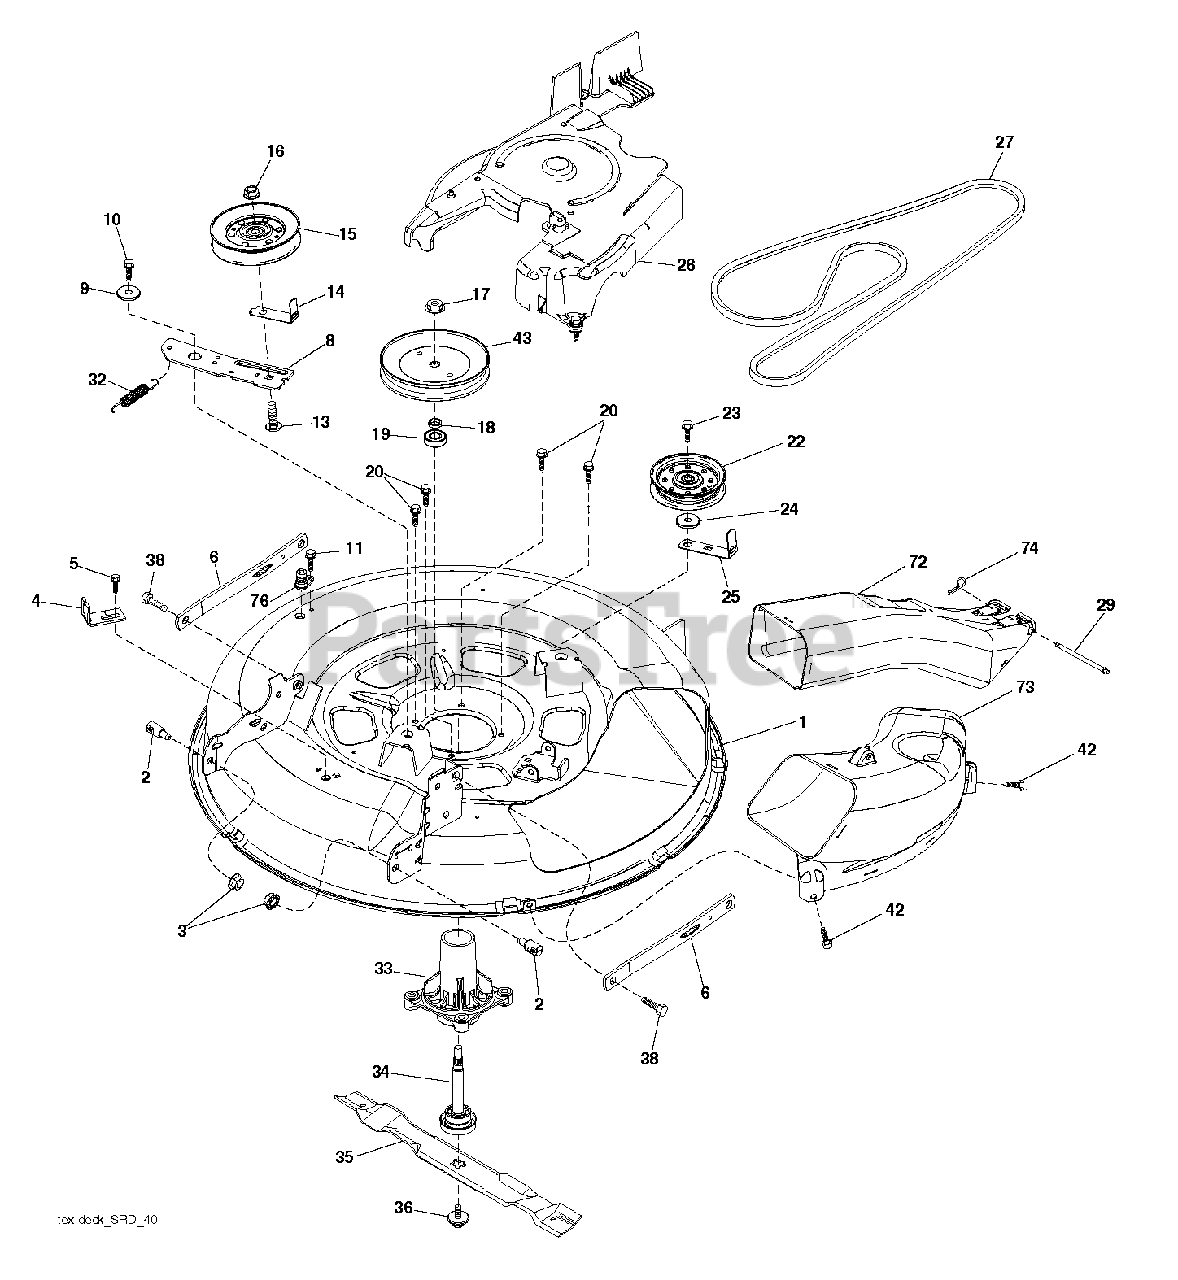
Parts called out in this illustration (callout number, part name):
1	DECK.WELDMENT.PNT.30"SRD
2	STUD.FASTNER.W/ANTI-ROTATE
3	NUT LOCK HEX FLANGE 5/16-18
4	BRACKET.CLUTCH.CABLE
5	BOLT.5/16HEX.WHS.HD
6	ARMS.SUSP.MOWER.REAR.SRD
8	ARM.IDLER.30"SRD
9	SPACER.RETAINER
10	SCREW 3/8-16X1
11	SCREW.1/4-20X5/8
13	BOLT.3/8-16X1.50
14	KEEPER, BELT IDLER
15	PULLEY.IDLER.4.25
16	NUT LOCK FLG 3/8-16 UNC
17	NUT.FLANGE.LOCK.TOP
18	WASHER.SPACER.MANDREL
20	SCREW, WASHER HEAD
22	PULLEY.IDLER.FLAT.46.PR.DR.
23	SCREW LT
24	WASHER
25	KEEPER.BELT.30"SRD
27	V-BELT.DRIVE.MOWER.30"
29	PIN.HINGE.30".SRD
32	SPRING.MOWER.DRIVE.ELECTRIC
33	HOUSING.MANDREL.4PT.
34	SHAFT.ASM.MDRL.N/GREASE.38
35	BLADE.MOWER.BAGGING.30"
36	BOLT.WASHER.ASM.7/16-2
38	BOLT.SHOULDER
42	SCREW, 3/8-16X3/4
43	PULLEY, MANDREL 6.5 PD
72	CHUTE.UPPER.SRD.30R"
73	CHUTE.LOWER.SRD.30R"
74	Retainer Spring
76	PORT.WASHOUT
